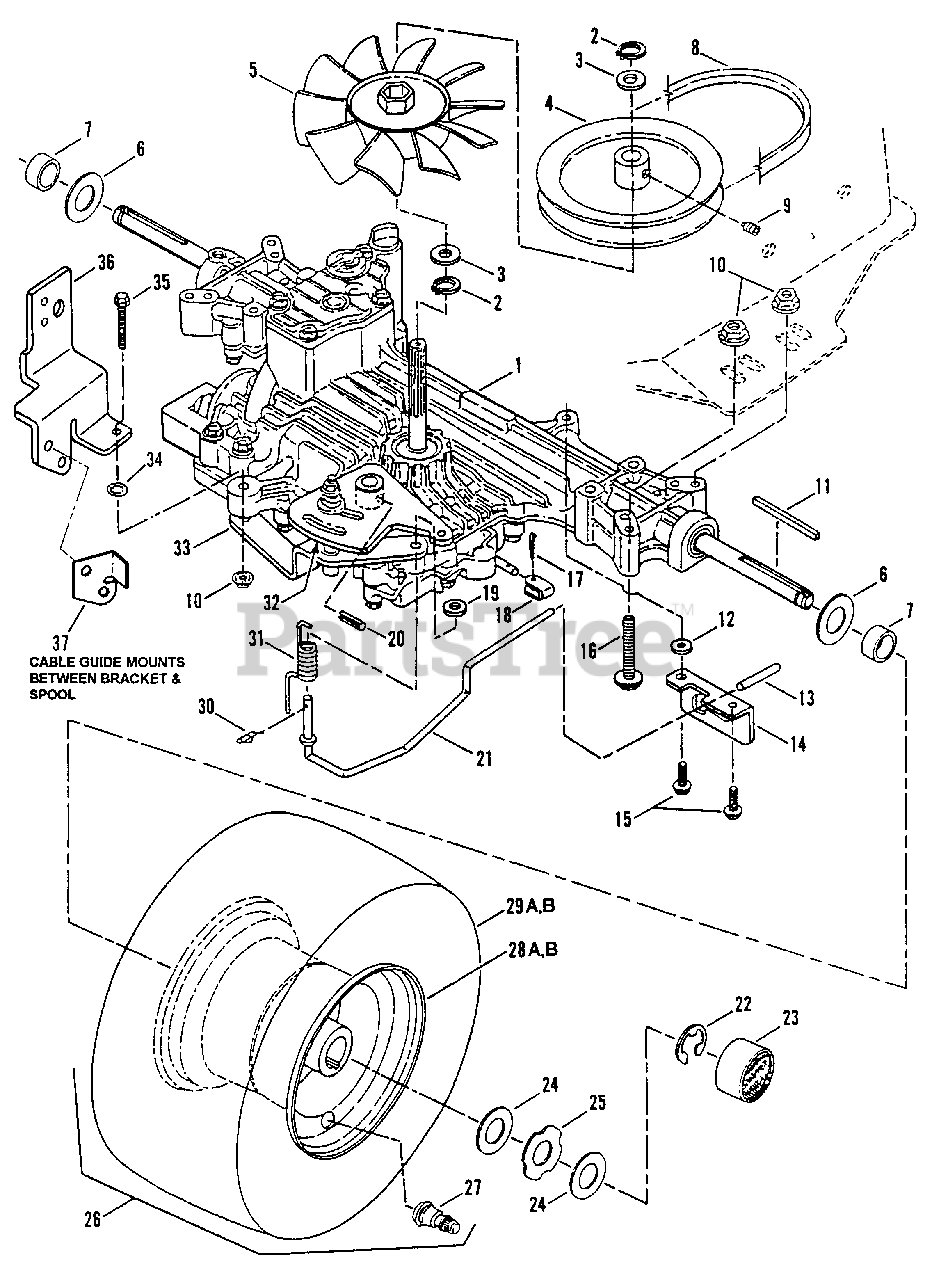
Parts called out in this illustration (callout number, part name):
1	TRANSAXLE, Hydro Drive, Tuff-Torq Mode K55
2	RING, Retaining
3	WASHER, Fan/Hub
4	PULLEY, Drive
5	FAN
6	WASHER, Flat, 3/4" I.D. x 1-1/2" O.D.
8	BELT, TTK50/K55 Traction Drive
9	SETSCREW, 1/4-20 x 5/16" Locking
10	NUT, 5/16-18 Hex Flange Lock, Grade 5
11	KEY, Square, 3/16 x 3/16 x 2 1/2"
12	WASHER, Flat, 13/32" I.D. x 3/4" O.D.
13	GRIP, Roll Release
14	DETENT, Roll Release
15	SCREW, 3/8-16 x 1-3/4" Self-Tapping
16	BOLT, 5/16-18 x 2-1/4" Hex Flange Lock
17	COTTER-PIN, 5/32 x 1"
18	LINK, Roll Release
19	WASHER, Flat, 11/32" I.D. x 11/16" O.D.
20	ROLL-PIN, Speed Control Arm
21	WIREFORM, Roll Release
22	RING, Retaining
23	HUB-CAP
24	WASHER, Flat, 3/4" x 1-5/16" O.D.
25	WASHER, Hub-Cap Retaining
26	ASSEMBLY, Rear Tire & Rim
27	VALVE, Air (Snap-in)
28A	RIM, 8 x 5.375
28B	RIM, 8 x 7.00
29A	TIRE, 18 x 7.50
29B	TIRE, 18 x 8.50
30	COTTER-PIN, 5/16 Self-Locking
31	SPRING, Torsion (Roll Release)
32	ASSEMBLY, Speed Control/Friction
33	SUPPORT, Friction Stud Assembly
34	RETAINER, 5/16 Bolt
35	BOLT, 5/16-18 x 2" Hex Flange Lock, Grade 5
36	BRACKET, Spool
37	GUIDE, Cable
